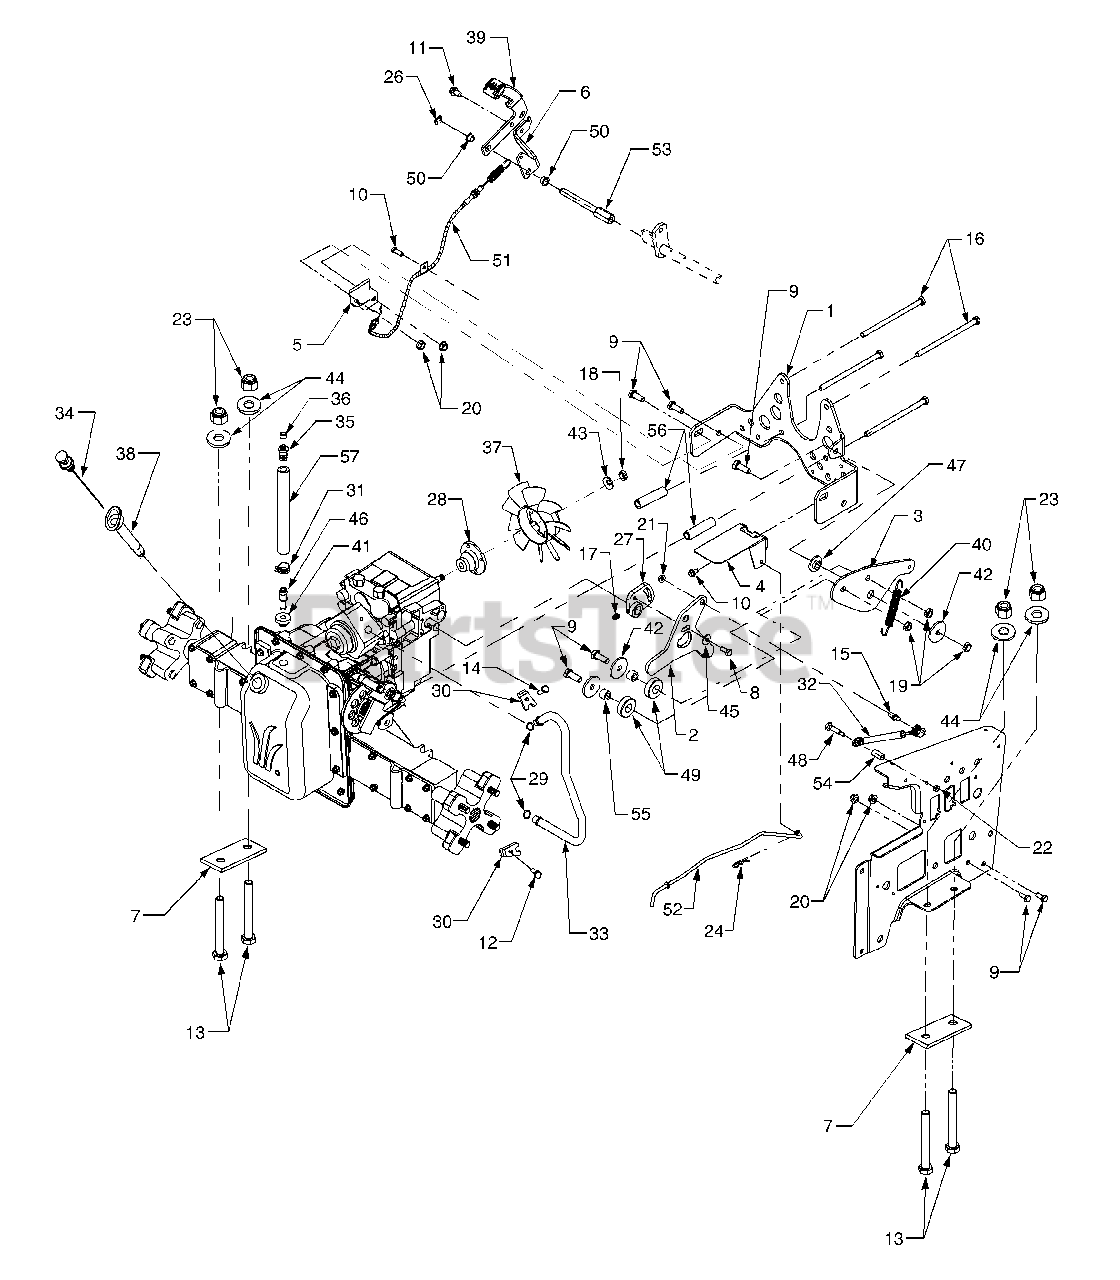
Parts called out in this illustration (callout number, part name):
1	Bracket, Torque
2	Plate, Hydro Neutral Return
3	Link, Neutral Return Bearing
4	Spring Plate, Hydro Bypass
5	Bracket, Cable Retainer
6	Bracket, Pedal Brace
9	Screw, Hex Cap, 3/8-16 x 1.0 GR5
10	Screw, Hex Wash. Hd. Tapp, 1/4-20 x .5
11	Screw, Hex Wash. Hd. Tapp, 3/8-16 x .75
12	Screw, Hex Wash. Hd. Tapp, 1/4-20 x .75
13	Screw, Hex Cap, 1/2-20 x 4.5 GR5
14	Screw, Hex Cap, 1/4-20 x .75 GR5
15	Ball Screw, 5/16-18 x .56
16	Screw, Hex Wash. Hd. Tapp 5/16-18 x 5.5 GR5
17	Screw, Set, 5/16 x .5
18	Nut, Hex Ctr. Lock Jam, 3/8-24
19	Nut, Hex Ctr. Lock Jam, 3/8-16
20	Nut, Hex Flange Lock, 3/8-16
21	Nut, Hex Flange Lock, 5/16-18
22	Nut, Hex, 1/4-20
23	Nut, Hex Insert Lock, 1/2-20
24	Pin, Internal Cotter
26	E-Ring, .5 Dia. Shaft
27	Arm, Hydro
28	Adapter, Pump
29	O-Ring, .426 ID x .566 OD x .070
30	Clamp, Tube
31	Clamp, Hose
32	Cylinder, Damper
33	Tube, Hydro Pickup
34	Dipstick, Transmission
35	Plastic Vent
37	Fan, Pump
38	Holder, Dipstick
39	Pedal, Diff Lock
40	Spring, Extension
42	Washer, Flat, .390 x 1.5 x .1
43	Washer, Bell, .401 x .87 x .063
44	Washer, Flat, .531 x 1.062 x .134
45	Washer, Flat, .26 x .72 x .06
46	Fitting, Tube
47	Spacer, Shoulder
48	Shoulder Bolt
49	Bearing, Ball
50	Bearing, Nylon Flange
51	Cable, Diff Lock
52	Rod, Pump Bypass
53	Shaft, Diff Lock
54	Spacer, .375 x .5 x 1.02
55	Spacer, .375 x .624 x .445
56	Spacer, Hydro, .3223 x .60 x 2.44
57	Fuel Line 8" Lg
